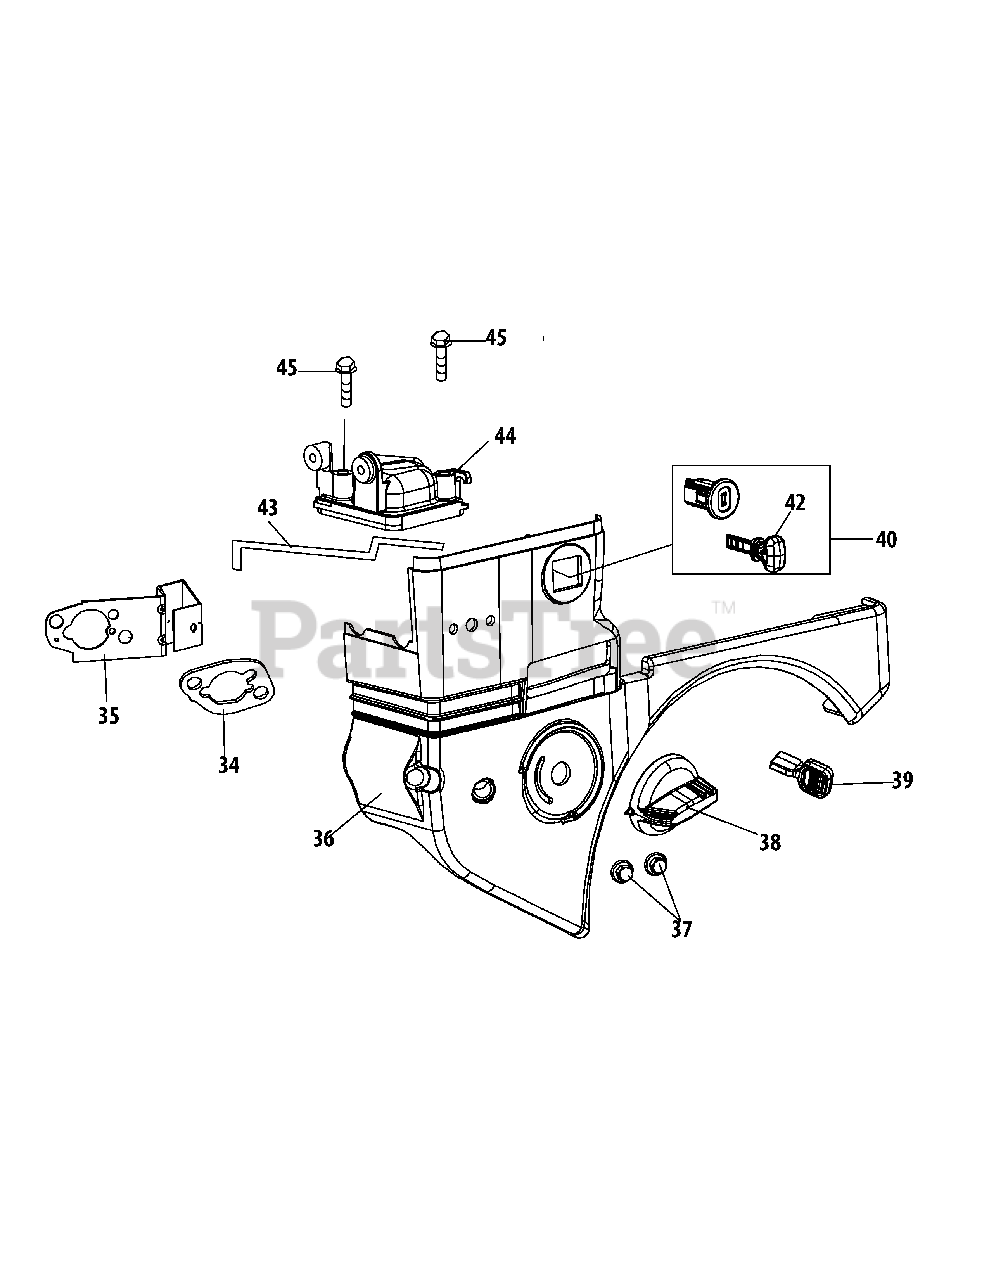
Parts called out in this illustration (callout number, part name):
34	Carburetor Gasket Plate
35	Choke Control
36	Air Cleaner Housing
38	Choke Knob
39	Throttle Control Knob
40	Key Switch
42	Key
43	Choke Push Rod
44	Heater Box
45	Bolt M6×25
